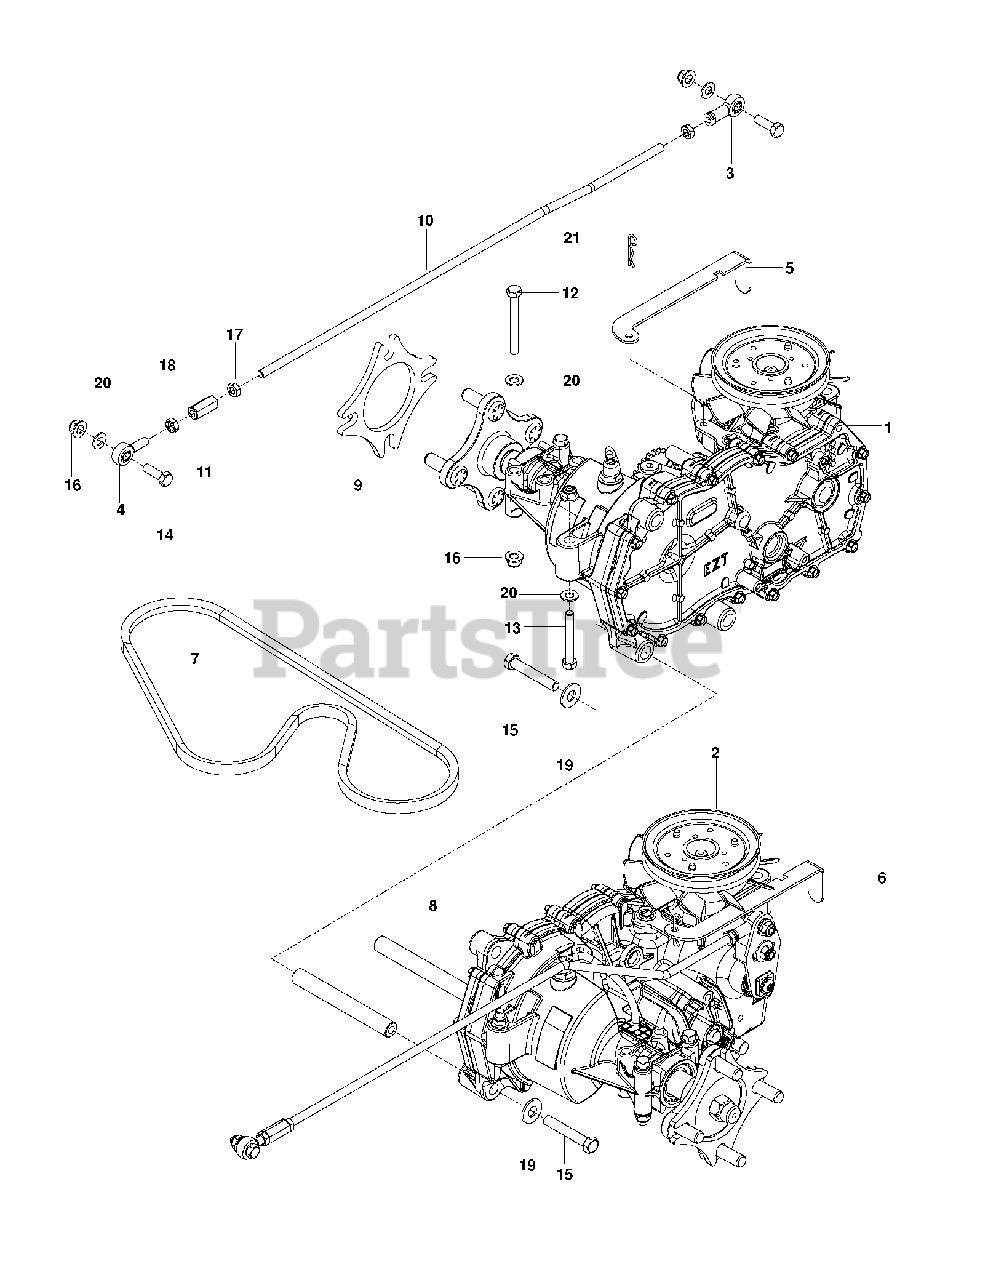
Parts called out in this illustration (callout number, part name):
1	HG_HYDRO RH
2	HG_HYDRO LH
3	RH ROD END
4	RB ROD.END.LH
5	RELEASE LEVER RH
6	RELEASE LEVER LH
7	BELT, EL 51.O4
8	SPACER, HYDRO
9	SPACER, WHEEL
10	CONTROL ROD
11	ROD END COUPLER
12	HCS 5/16C X 2-3/4
14	HCS 5/16C X 1
15	HCS 3/8C X 2 1/4
16	5/16-18 NYLOC FLANGE NUT
17	NUT 5/16-24 UNF HEX JAM
18	NUT 5/16F LEFTHAND
19	RP WASHER 3/8 FLAT
20	FLAT WASHER 5/16 SAE
21	HAIRPIN #2
